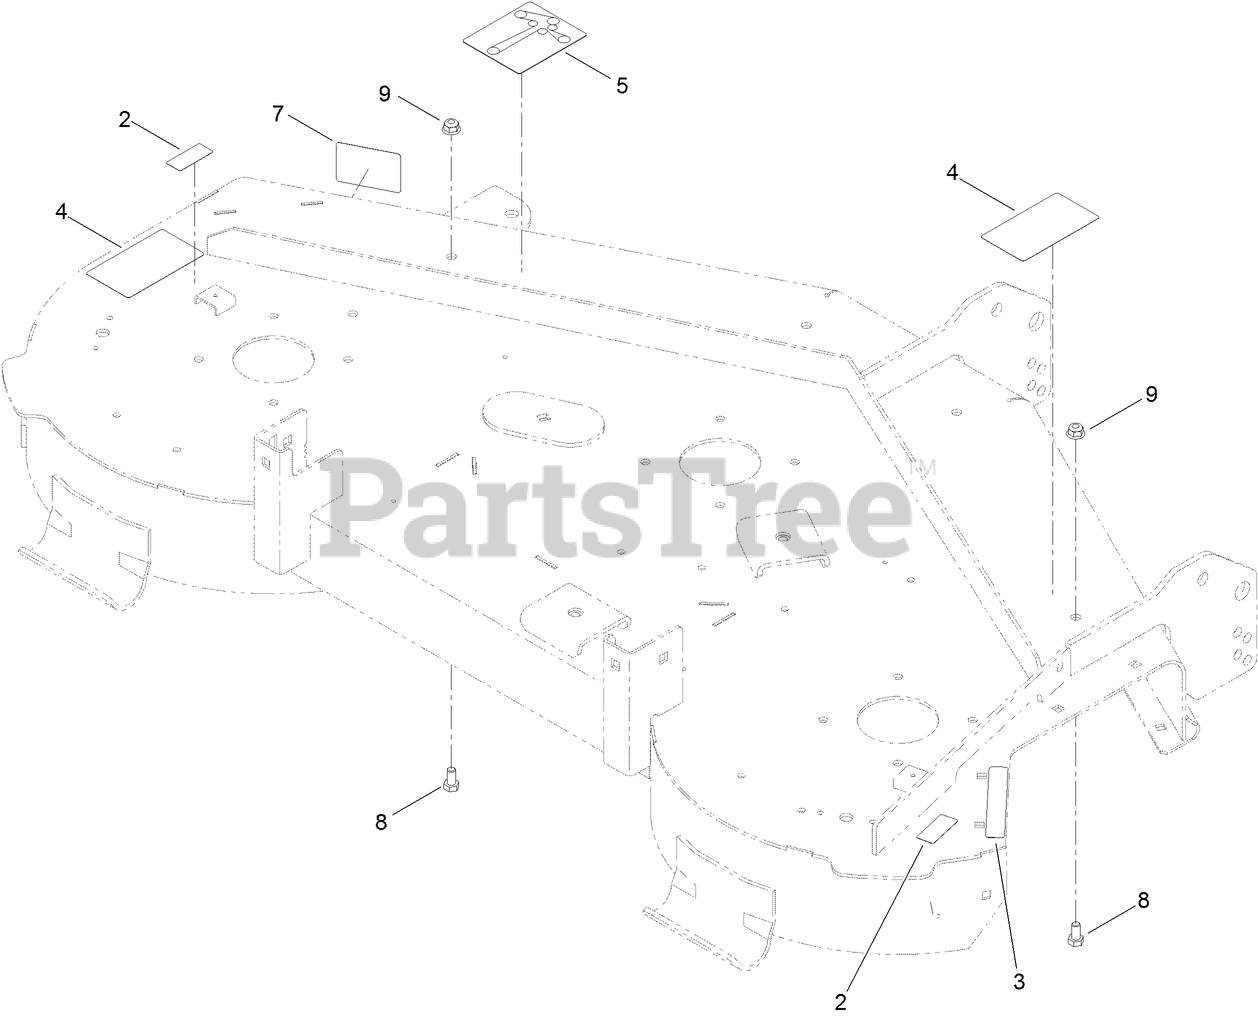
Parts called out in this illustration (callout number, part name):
2	DECAL-DANGER
3	DECAL-DANGER
4	DECAL-DANGER
5	DECAL-ROUTING, BELT
7	DECAL-SCALP, ANTI
8	SCREW-HH
9	NUT-HF, NI
